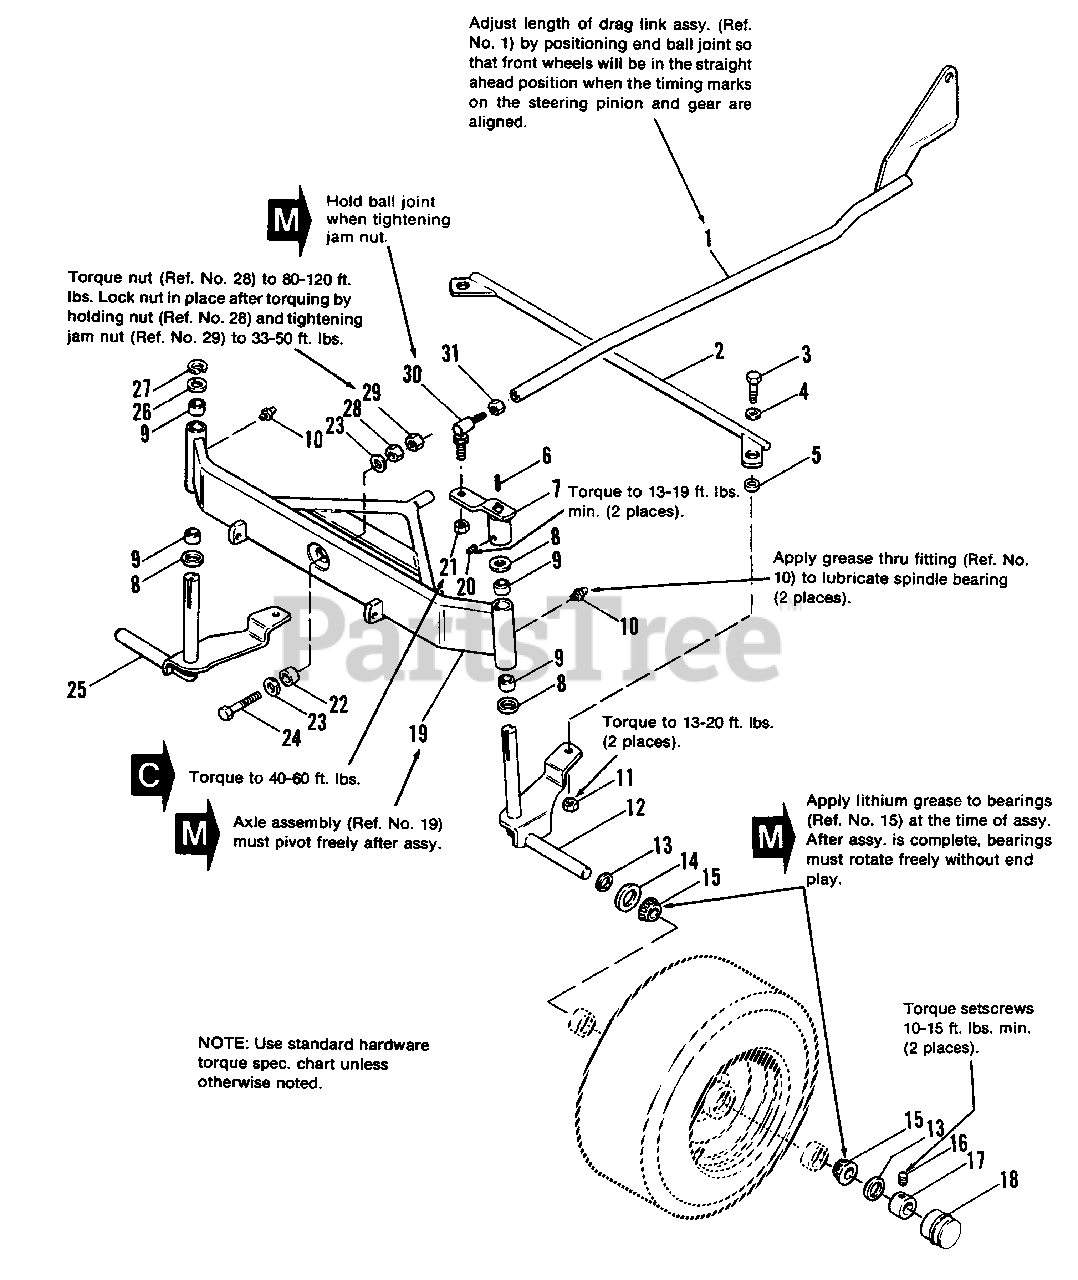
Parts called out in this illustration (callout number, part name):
1	LINK ASSY., Drag
2	ROD ASSY., Tie
3	CAPSCREW, Hex Hd., 3/8-16 x 1
4	WASHER, Plain, 3/8
6	KEY, Square
7	ARM ASSY., Steering
10	FITTING, Grease
11	LOCKNUT, Hex, 3/8-16
12	SPINDLE ASSY., LH
15	CONE, Bearing
16	SETSCREW, 5/16-18 x 5/16
17	COLLAR, Set
18	CAP, Hub
19	AXLE ASSY., Front
20	SETSCREW, 5/16-18 x 1/2
21	LOCKNUT, Hex, 1/2-20
23	WASHER, Plain, 1/2
24	CAPSCREW, Hex Hd., 1/2-13 x 2-1/4
25	SPINDLE ASSY., RH
27	RING, Retaining
28	LOCKNUT, Hex, 1/2-13
29	LOCKNUT, Hex, Jam, 1/2-13
30	BALL, Joint
31	LOCKNUT, Hex, Jam, 1/2-20
